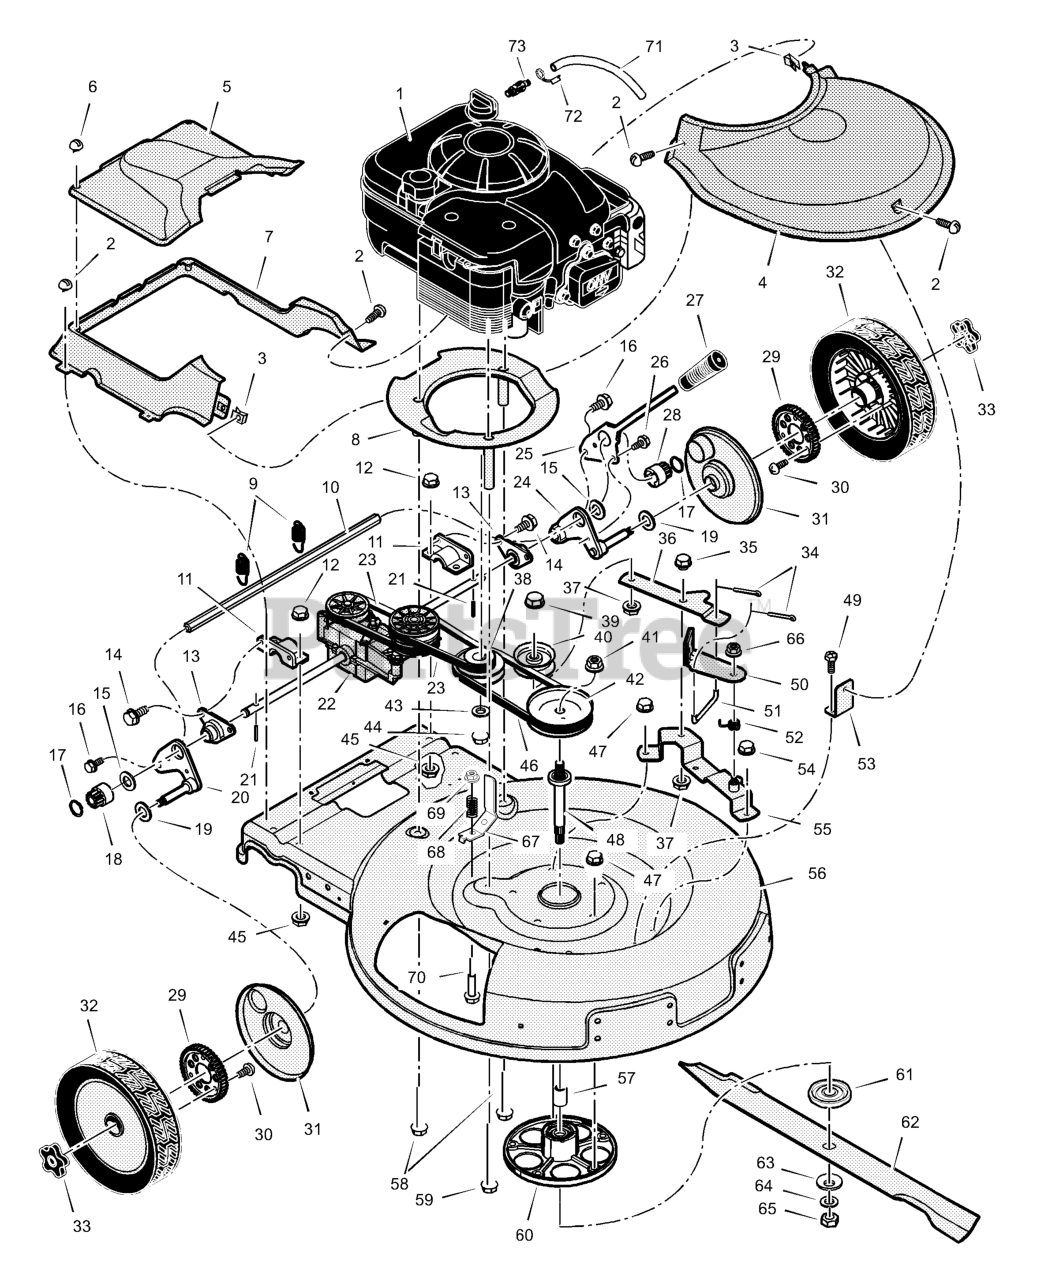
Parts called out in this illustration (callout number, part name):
1	Engine *
2	Screw
3	Tinnerman, "U"
4	Cover, Front
5	Cover, Transmission
7	Cover, Rear
8	Base Assembly, Engine
9	Spring, Extension
10	Crossbar, Rear
11	Bearing, Axle Support
12	Screw
13	Retainer Assembly, Axle Bearing
15	Washer, Thrust
17	Retainer Ring
18	Gear, Right Pinion
19	Washer, Spring
20	Bracket Assembly, Right Axle
21	Pin, Drive
22	Transmission *
23	Belt, Transmission
24	Bracket Assembly, Left Axle
25	Lever, Spring Height Adjuster
26	Screw, Tap
27	Knob, Height Adjuster
28	Gear, Left Pinion
30	Screw, Tap
31	Cover, Dust
32	Wheel, Drive
33	Knob, Axle
34	Pin, Cotter
35	Bolt, Shoulder
36	Idler Arm
37	Nut, Flange
38	Pulley, Engine
39	Screw
40	Pulley, Idler
41	Nut, Blade Pulley
42	Pulley, Blade
43	Washer, Split
44	Screw
46	Belt, Blade Drive
47	Bolt
48	Jackshaft
50	Brake Assembly, Blade
51	Link, Blade Brake
52	Spring, Torsion
53	Bracket, Front Cover
55	Support Assembly, Idler & Brake
57	Spacer, Jackshaft
58	Bolt, Short Engine Mount
59	Bolt, Long Engine Mount
60	Mandrel Assembly
61	Adapter, Blade
63	Washer, Cup
65	Nut, Blade Mount
66	Nut
67	Guide, Belt
69	Nut
71	Tube, Oil Drain
72	Cap, Oil Drain
73	Valve, Oil Drain
